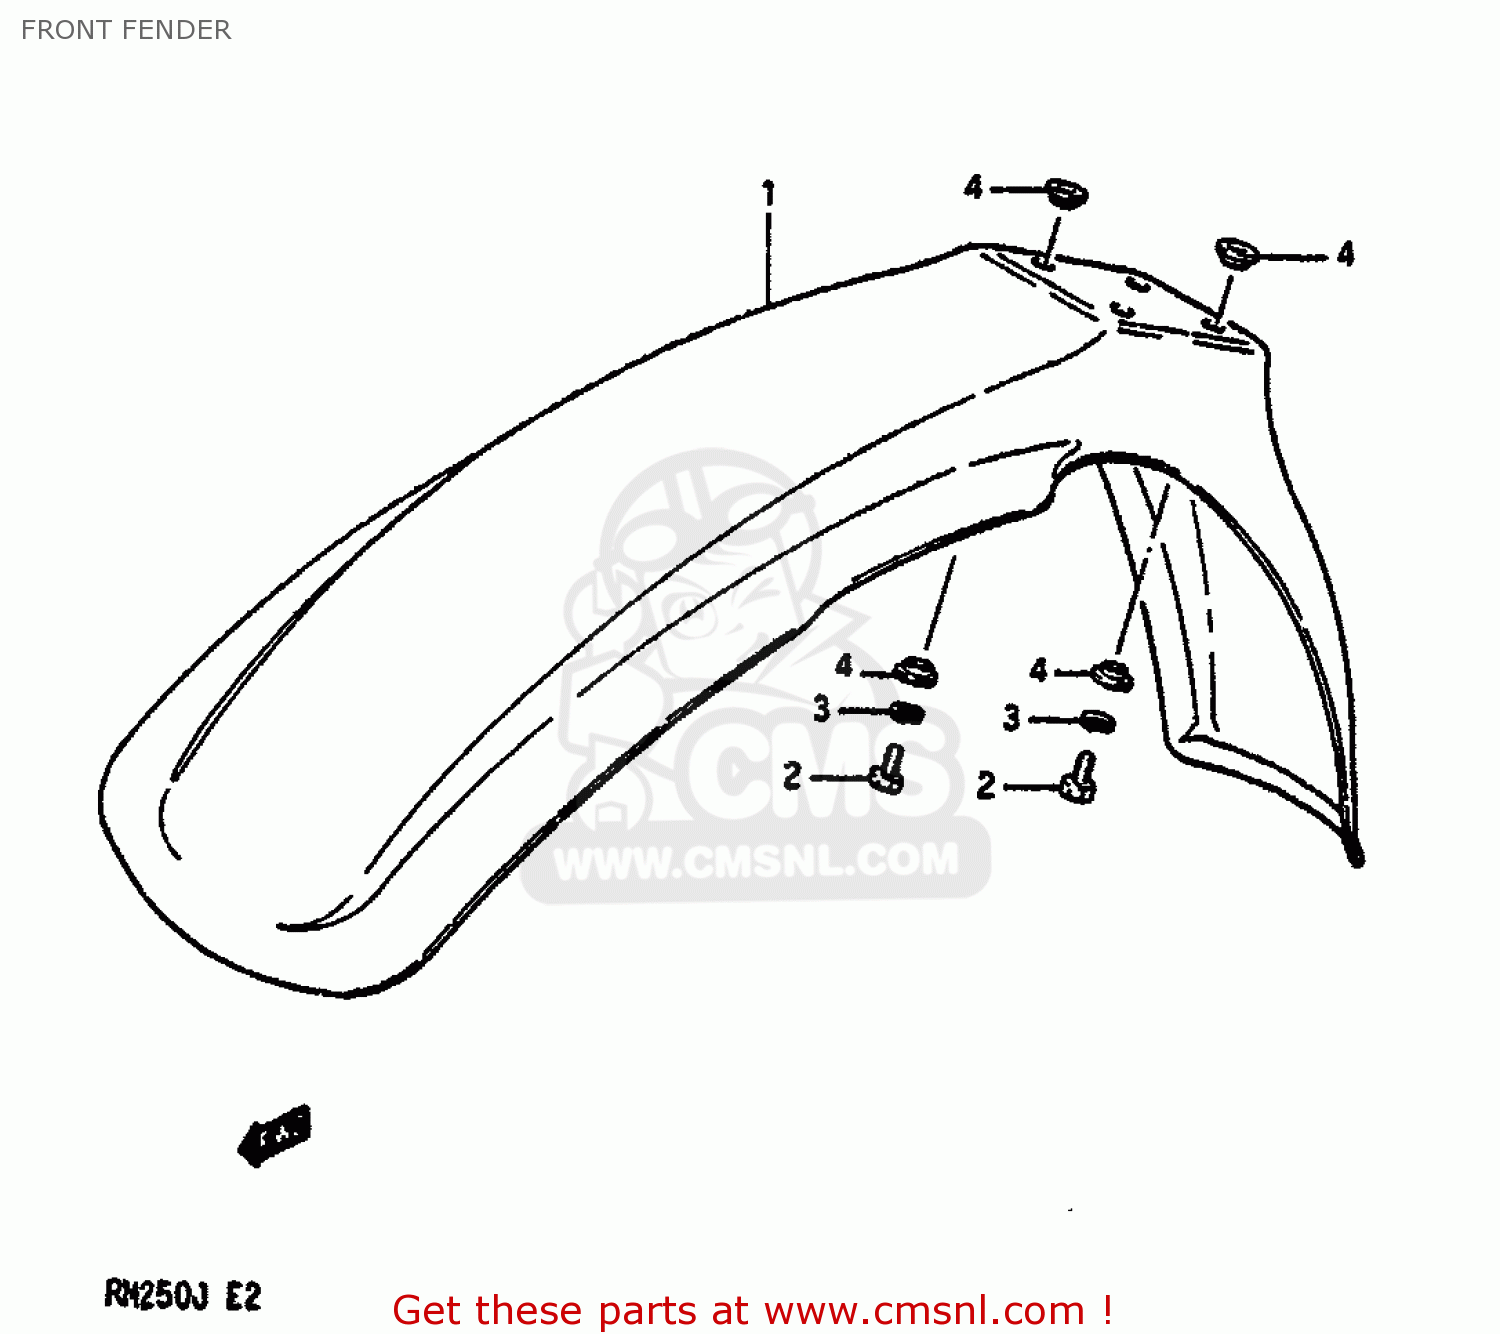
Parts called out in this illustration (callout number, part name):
1	FENDER,FR
2	BOLT
3	WASHER,LOCK
4	WASHER
